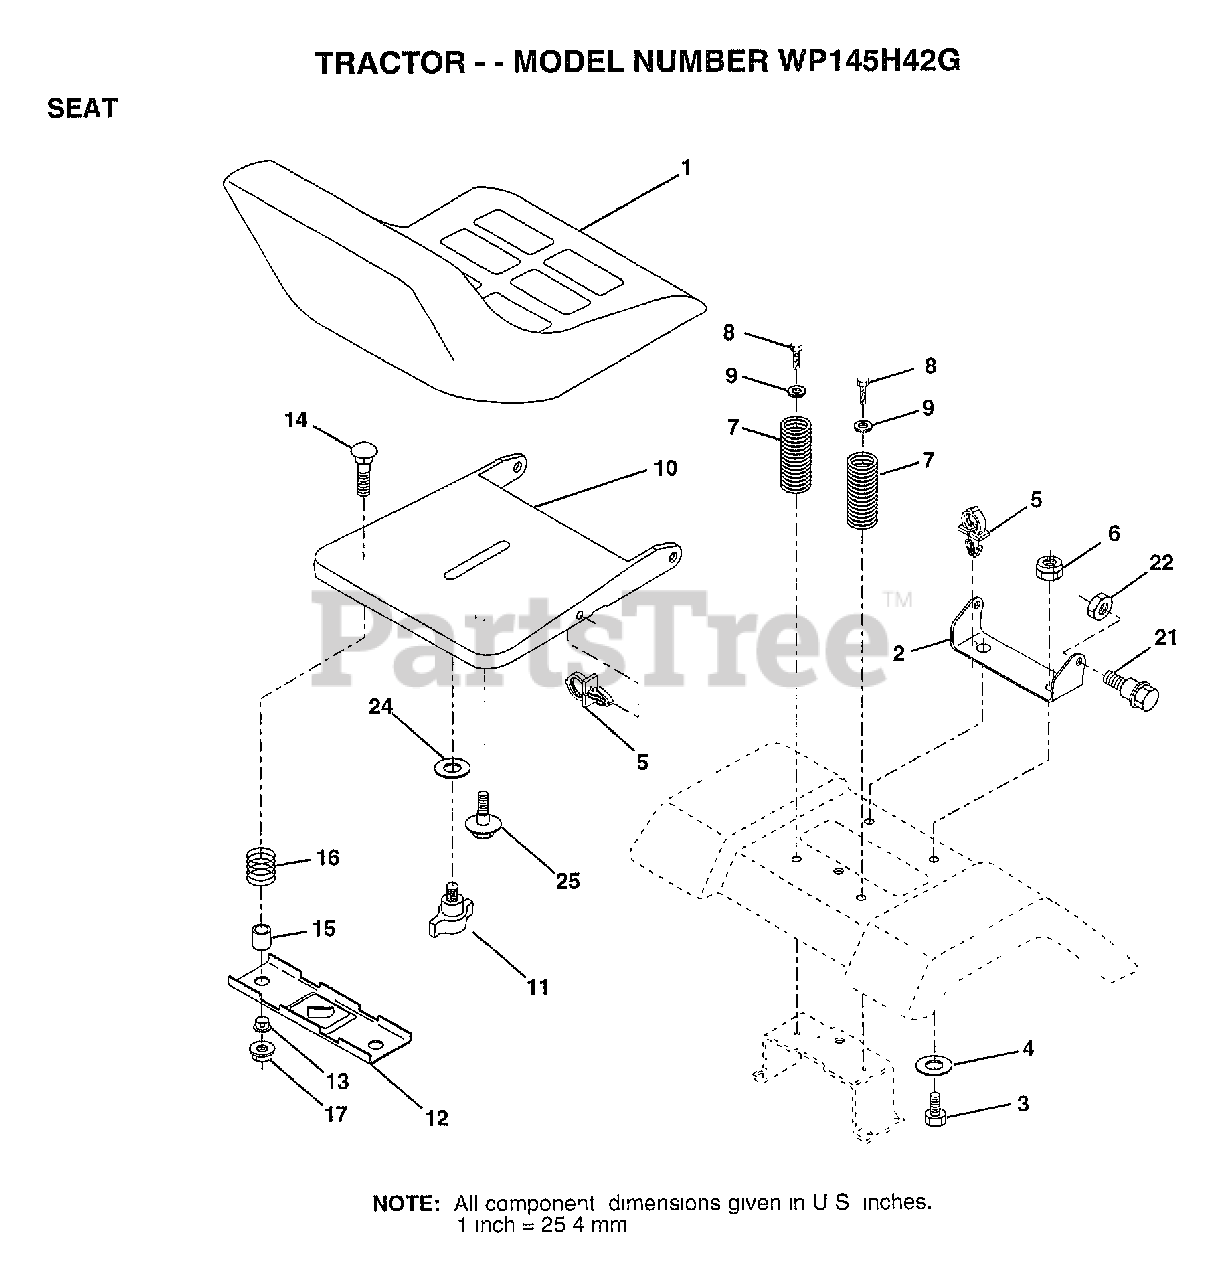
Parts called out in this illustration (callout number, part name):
2	BRACKET PVT SEAT
3	BOLT
4	WASHER PM
5	CLIP.PUSH-IN.HING
6	NUT
7	SPRING COMPRESSIO
8	SCREW GTV
9	WASHER
10	PAN-SEAT
11	KNOB.SEAT.ADJ.WINGNUT
12	BRKT SWITCH
13	BUSHING
14	BOLT-RD HD SQ NK
15	SPACER SPLIT
16	SPRING COMPRESSED
21	"BOLT,SHOULDER"
24	WASHER
25	"BOLT,SHOULDER"
